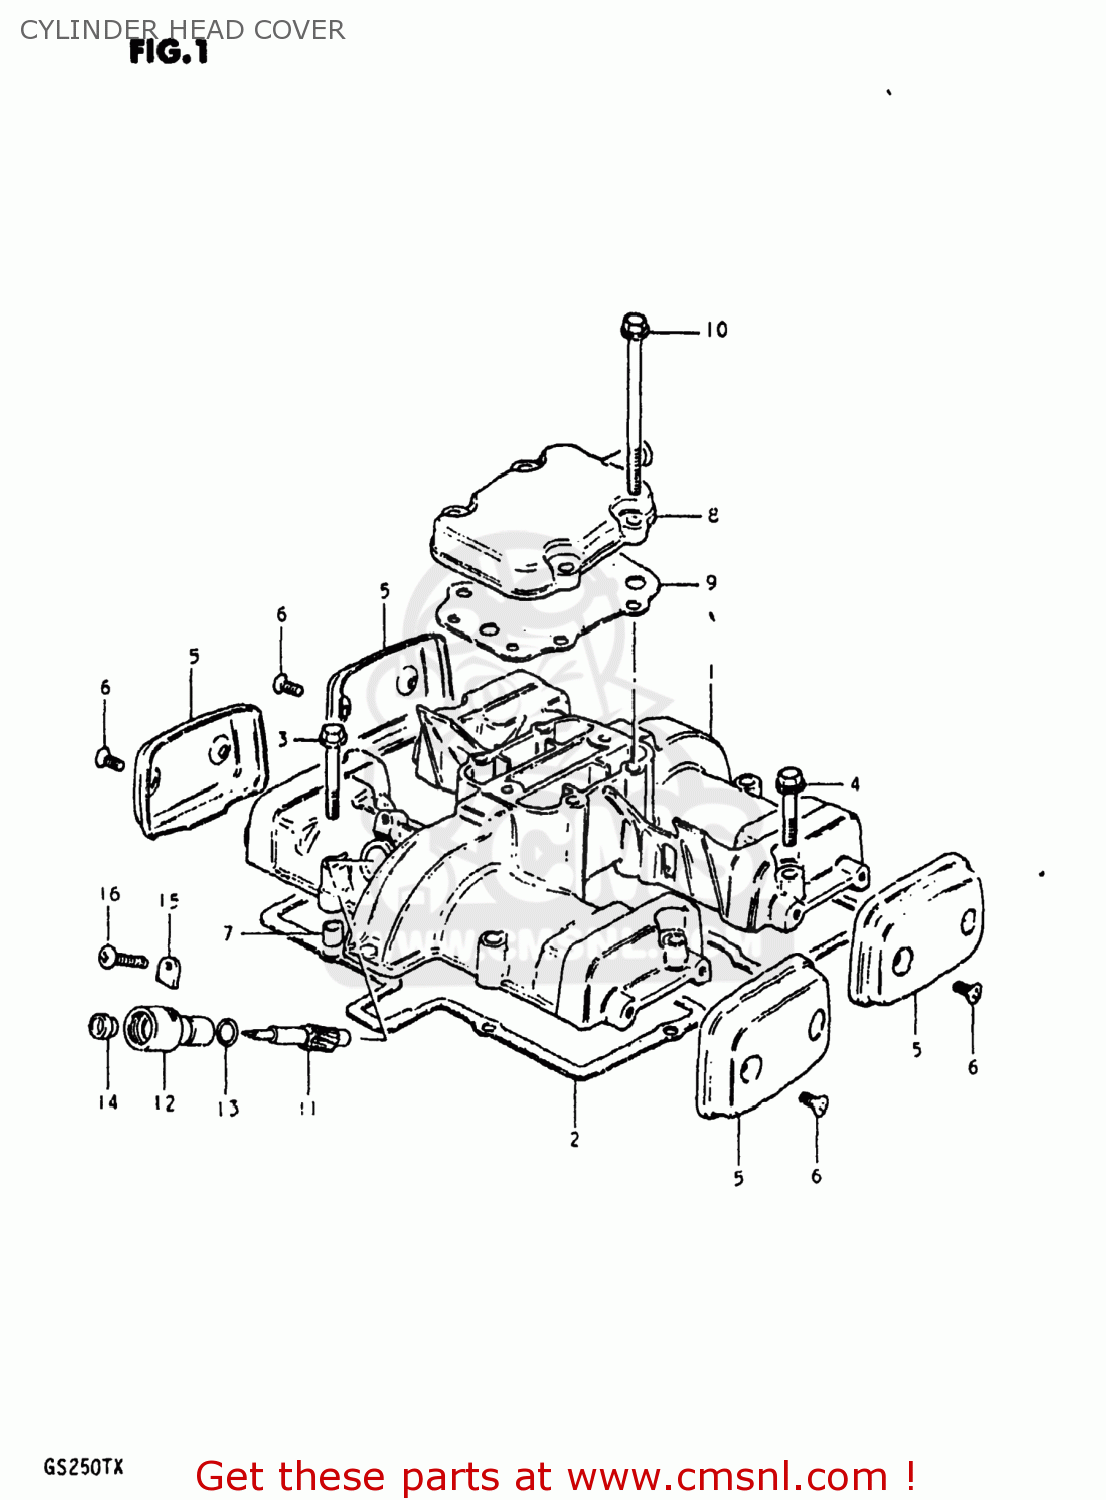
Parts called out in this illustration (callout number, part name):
1	COVER,CYLINDER HEAD
2	GASKET,CYLINDER HEAD COVER (MCA)
3	BOLT
4	BOLT 6X35
5	UNION,CYLINDER HEAD OIL
6	SCREW 5X12
7	PIN(6.2X8X11)
8	COVER,BREATHER
9	GASKET,BREATHER COVER (MCA)
10	BOLT (6X75)
11	GEAR,TACHOMETER DRIVEN
12	SLEEVE,TACHOMETER DRIVE
13	SEAL,TACHOMETER DRIVEN
14	SEAL,OIL(5X12X8)
15	PLATE,TACH DRIVE GEAR SLEEVE
16	SCREW(5X12)
